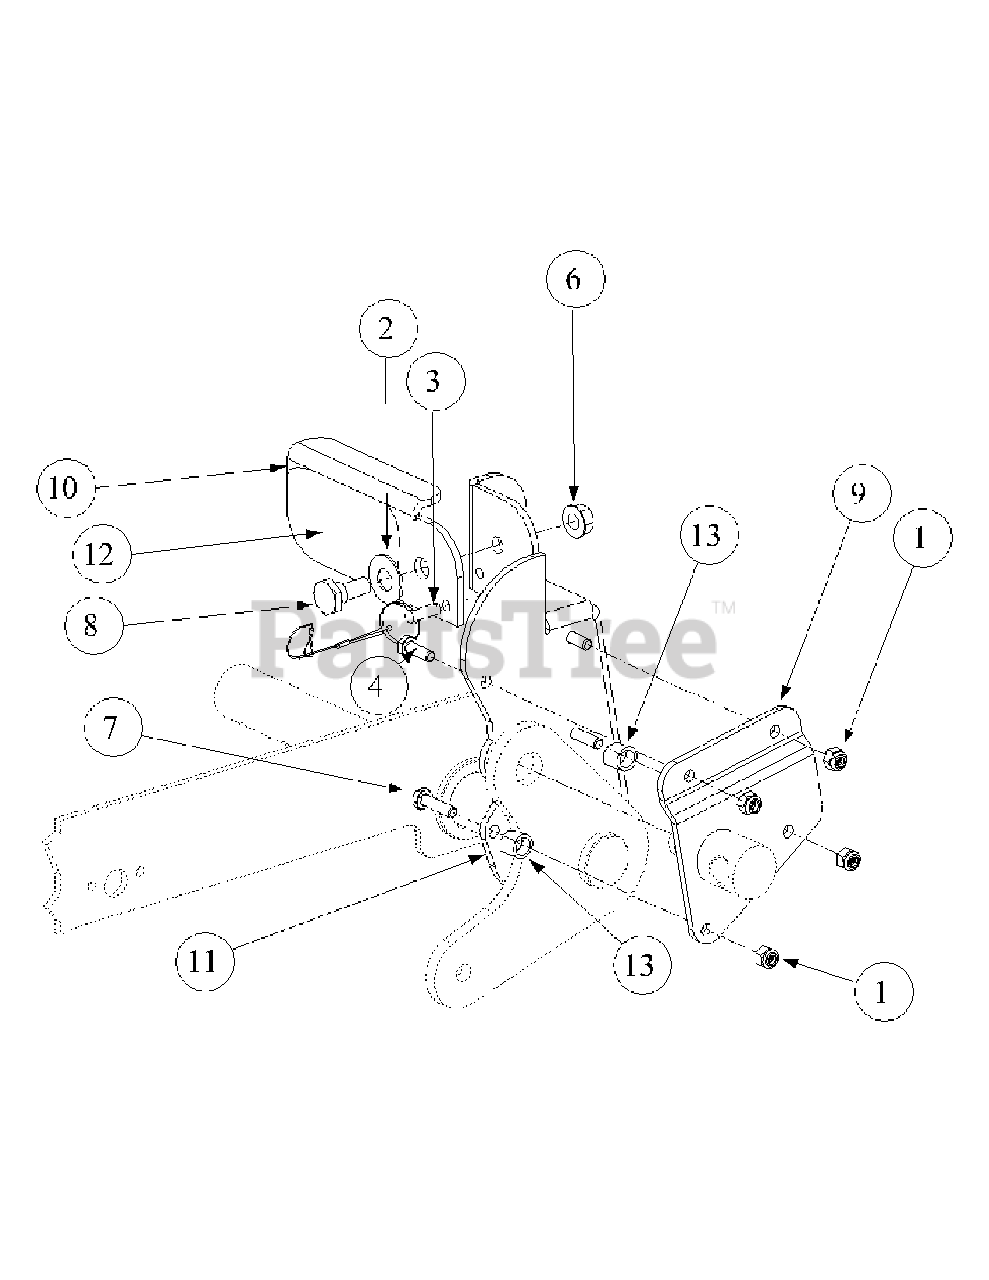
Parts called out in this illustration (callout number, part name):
1	Lock Nut, Nylon Insert, 1/4-20
2	Washer, 1/2 x 1 Shim
3	Detent Pin w/12" Lanyard
4	Hex Cap Screw, 1/4-20, .75
6	Hex Nut, Flange Lock 3/8-16
7	Hex Cap Screw, 1/4-20, 1.00
8	Shoulder Screw, .50 x .27 Lg., 3/8-16 1
9	Foot Lift Backup Pedal
10	Deck Foot Pedal Lift
11	Deck Foot Pedal Lift
12	Deck Foot Lift Pad
13	Turnbuckle Sleeve
